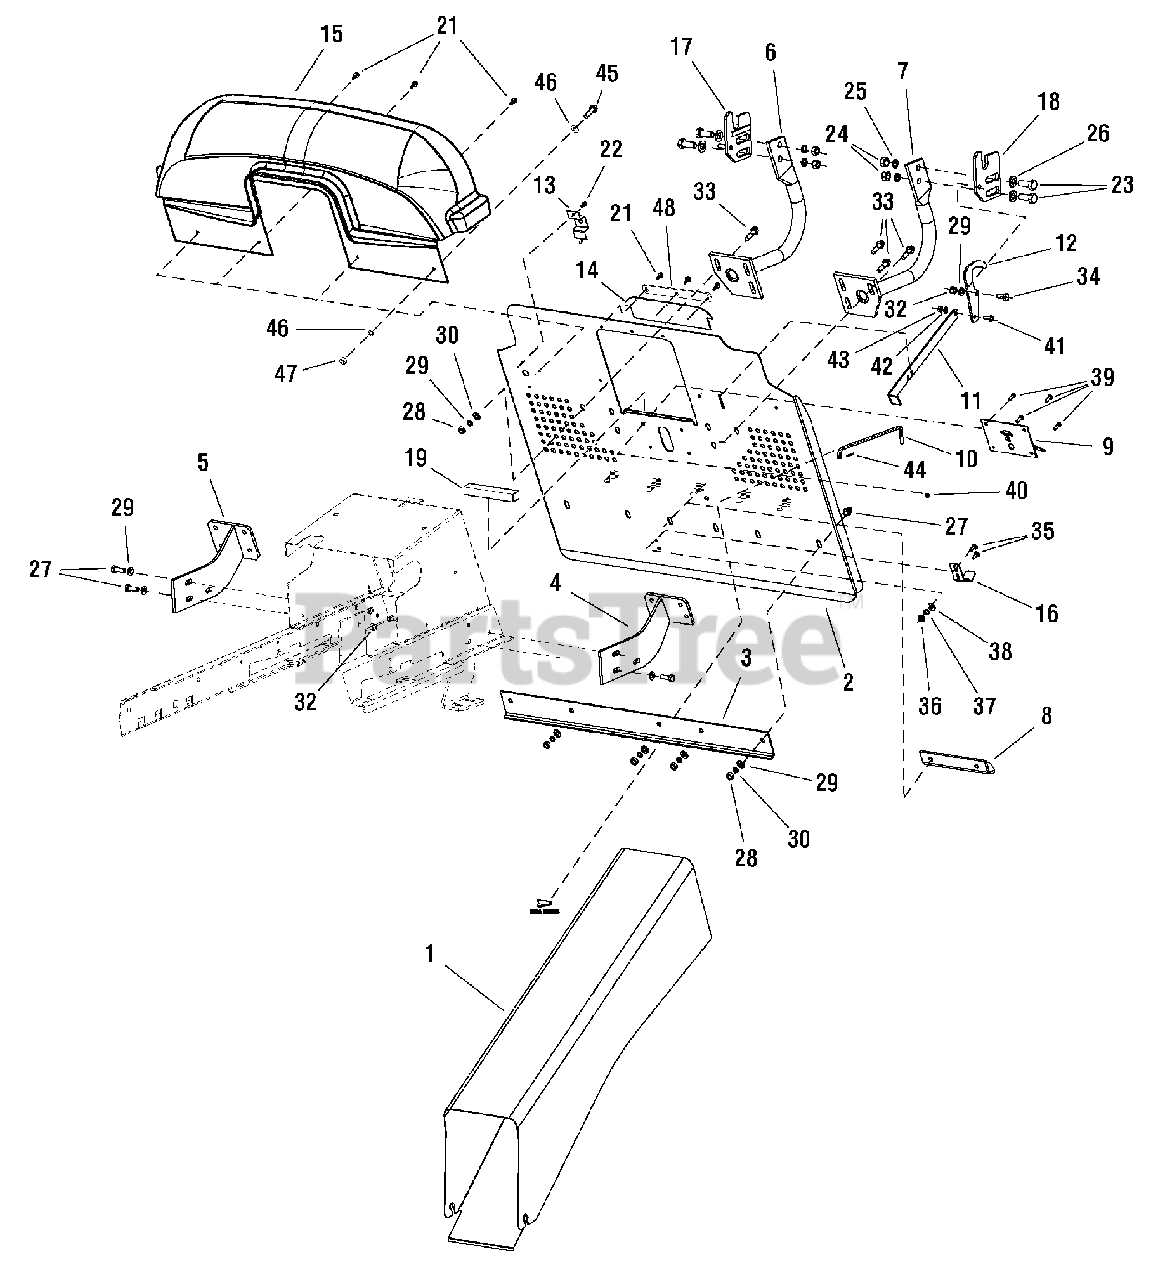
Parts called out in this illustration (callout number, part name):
2	BACK PLATE
4	HOLDER, Back Plate, L.H.
5	HOLDER, Back Plate, R.H.
6	HOLDER, Collector, R.H.
7	HOLDER, Collector, L.H.
9	SWITCH, Full Collector
10	TIE ROD, Bypass 0-8045-260
11	LATCH, Tie Rod
13	COVER, Switch
14	PAD, Rubber 1-1332-332
15	COVER, Plastic
16	SPRING COLLECTOR, Lock
17	HOLDER, Adjustable, Right
18	HOLDER, Adjustable, Left
19	RUBBER EDGE
21	SCREW, ST 5.5 x 19 DIN 7504-K BN1880
22	SCREW, ST 4.2 x 9.5 DIN 7504-K BN1880
23	BOLT , M12 x 30
25	WASHER, 13
26	WASHER, 12
27	BOLT, M8 x 25 DIN 6921 8.8
29	WASHER, 8.4
30	WASHER, 8
33	BOLT, M8 x 30 DIN 6921 8.8
34	BOLT, M8 x 40
35	BOLT, M5 x 16
37	WASHER, 5.3
38	WASHER, 5
39	BOLT, M5 x 16
41	BOLT, M6 x 16
42	WASHER, 6.4
44	SPINDLE, 2 x 20
45	BOLT, M4 x 16
46	WASHER, 4.3
